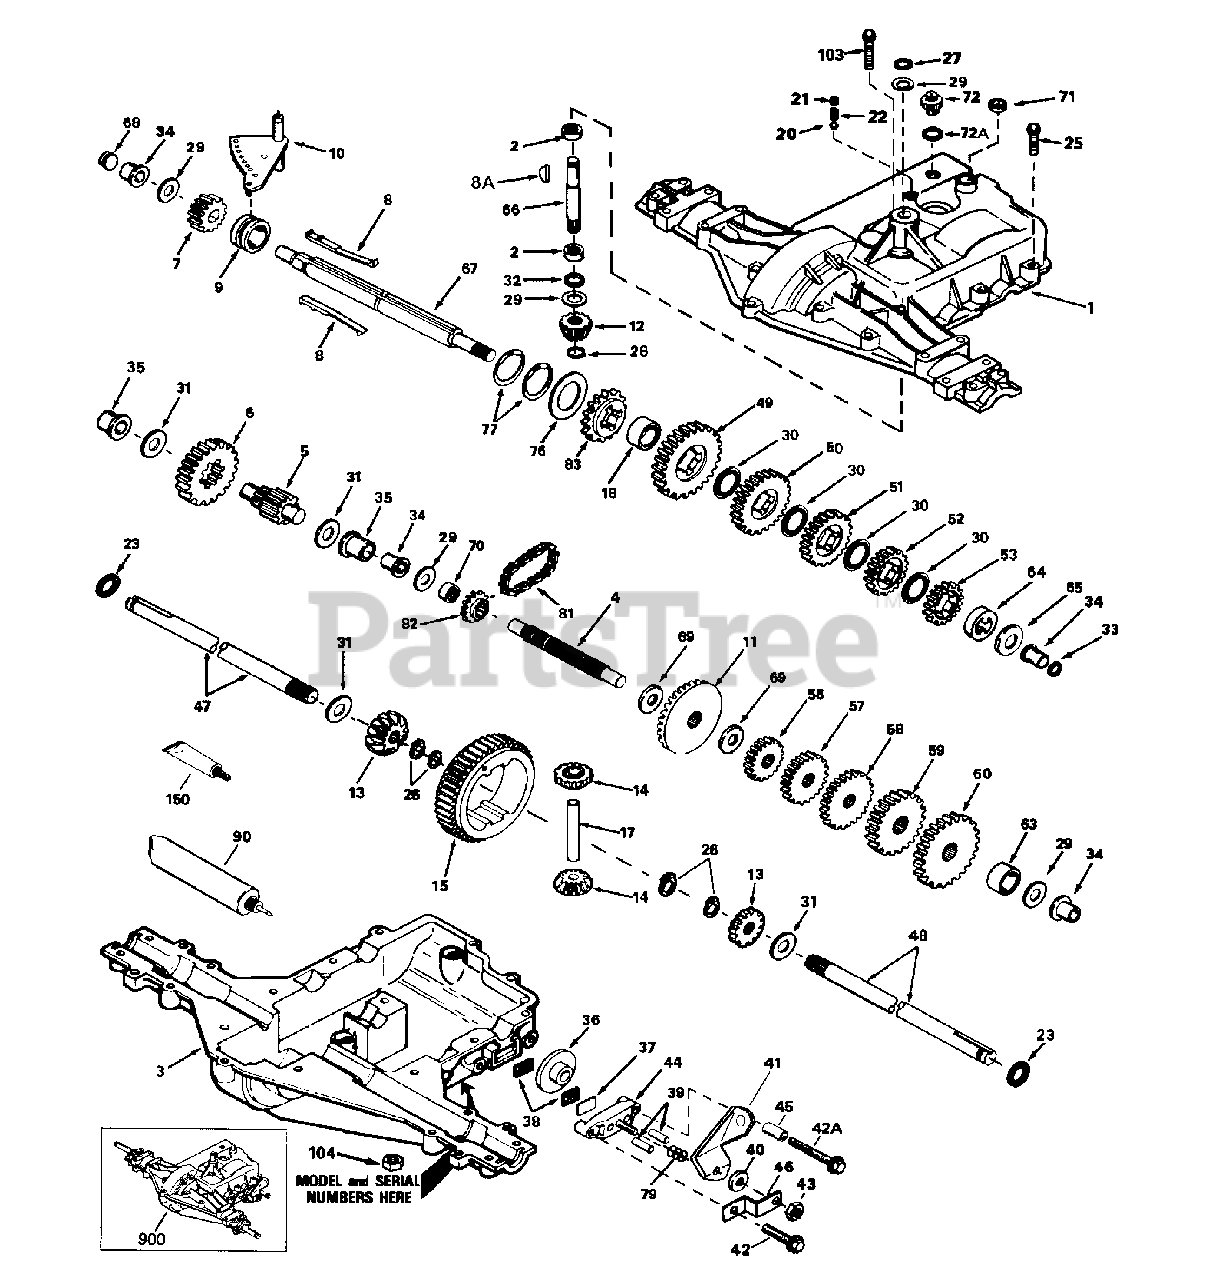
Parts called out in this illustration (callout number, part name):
1	Cover, Transaxle
2	Bearing, Needle
3	Case, Transaxle
4	Shaft, Counter
5	Shaft and Pinion Assembly, Output
6	Gear, Output
7	Gear, Spur, 15 Teeth
8	Key, Shift
8A	Key, Woodruff
9	Collar, Shifter
10	Rod and Fork Assembly, Shift
11	Gear, Bevel, 42 Teeth
12	Bevel Pinion, Input
13	Gear, Bevel
14	Gear, Bevel Pinion
15	Gear, Ring
17	Pin, Drive
18	Spacer, Neutral
20	Ball, Steel 5/16" diameter
21	Set Screw 3/8-16 x 3/8
23	Ring, Seal
25	Screw, Flanged Hex Head, Thread Forming 1/4-20 x 1-1/4
26	Ring, Retainer
27	Ring, Retainer
28	Ring, Retainer
29	Washer, Thrust
30	Washer, Thrust
32	"O" Ring
33	Seal, Square Cut
34	Bushing, Flanged
35	Bushing, Flanged
36	Disk, Brake
37	Plate, Brake Pad
38	Pad, Brake
39	Pin, Dowel
40	Washer, Flat
41	Lever, Brake
42	Screw, Flanged Hex Head, Thread Forming 1/4-20 x 1-1/4
42A	Screw 1/4-20 x 2-1/4
43	Locknut 5/16-24
44	Holder, Brake Pad
46	Bracket, Brake Lever
47	Axle 11-5/16" long
48	Axle 16-1/2" long
49	Gear, Spur, 37 Teeth, Steel (1 st)
50	Gear, Spur, 30 Teeth (2 nd)
51	Gear, Spur, 25 Teeth (3 rd)
52	Gear, Spur, 22 Teeth (4 th)
53	Gear, Spur, 19 Teeth, Steel (5 th)
56	Gear, Spur, 12 Teeth (1 st)
57	Gear, Spur, 20 Teeth (2 nd)
58	Gear, Spur, 25 Teeth (3 rd)
59	Gear, Spur, 28 Teeth (4 th)
60	Gear, Spur, 31 Teeth (5 th)
65	Washer, Thrust
66	Shaft, Input
67	Shaft, Brake, 4 Keyed
69	Washer, Thrust
71	Seal, Square Cut
72	Plug, Threaded 9/16-18
72A	"O" Ring
76	Washer, Thrust
77	Ring, Retaining, Inverted
79	Spring, Brake
81	Chain, Roller (Number 41 Chain, 24 Links)
82	Sprocket, 9 Teeth (Reverse)
83	Sprocket, 18 Teeth (Reverse)
90	Grease, Bentonite, 32 Ounce Bottle
103	Screw 1/4-20 x 2
104	Locknut 1/4-20
150	Gasket Eliminator (Loctite #515)
900	Replacement Transaxle
